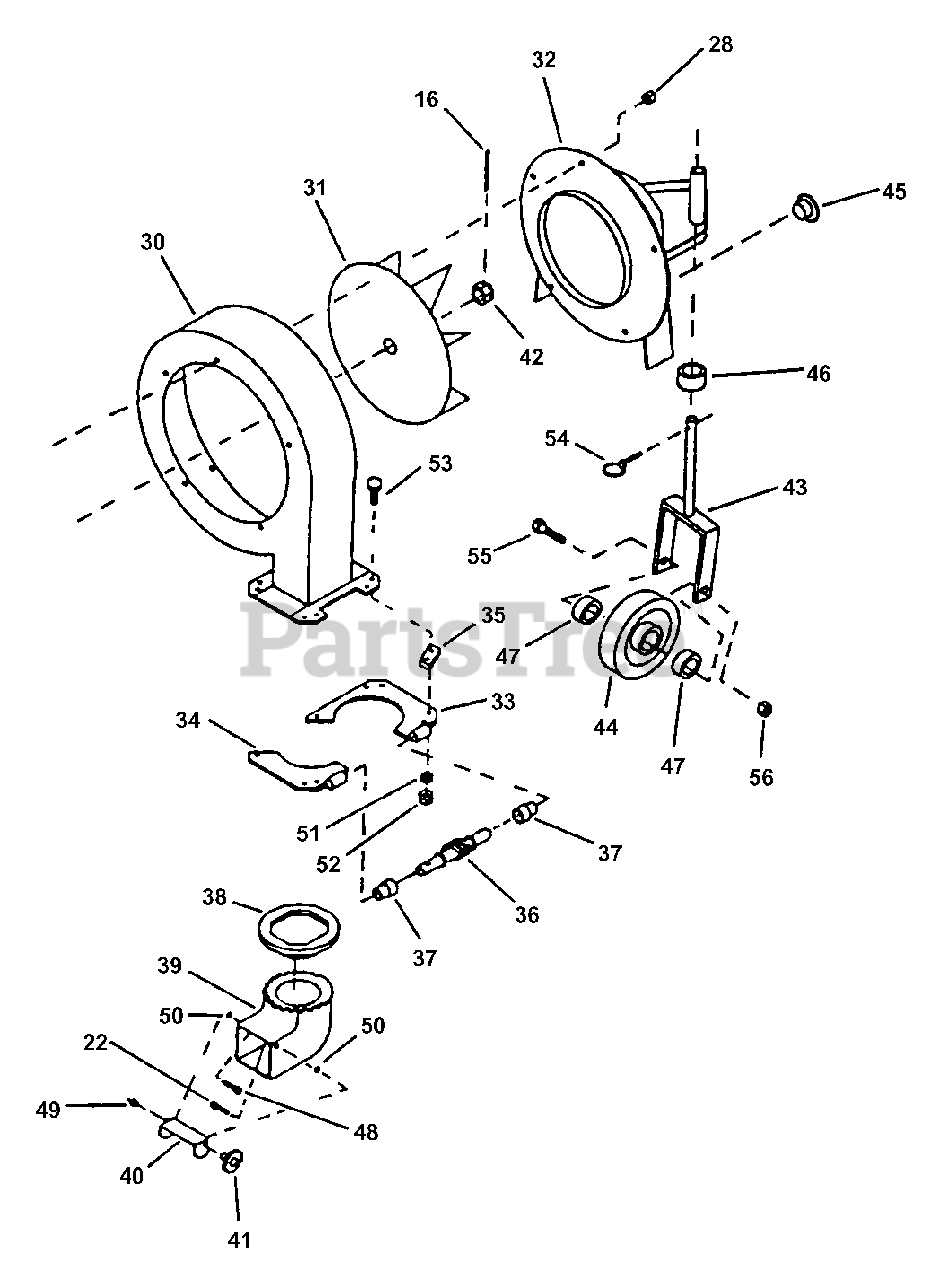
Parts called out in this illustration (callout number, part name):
16	PIN, 3/16" Dia. x 2" Cotter
22	BOLT, 5/16-18 x 1" Square Neck Carriage
28	NUT, 5/16-18 Hex Flange Lock, Grade 5 or B
30	HOUSING, Impeller (weldment)
31	IMPELLER (weldment)
32	COVER, Intake (weldment)
33	BRACKET, Rotation
34	PLATE, Retaining
35	SPACER, Rotation
37	BUSHING, Plastic, 1-5/16" long
38	RING, Nylon
39	NOZZLE, Air Blast
40	DEFLECTOR
41	KNOB, 5/16"
42	NUT, 1" Castle
43	SUPPORT, Wheel (weldment)
44	ASSEMBLY, Wheel & Tire
46	SPACER (for wheel support)
47	SPACER (for wheel)
48	BOLT, 5/16-18 x 3/4" Square Neck Carriage, Grade 5
49	NUT, 5/16-18 Hex Nyloc
50	WASHER, 11/32" Diameter
51	WASHER, 1/4" Lock
52	NUT, 1/4-20 Hex, Grade 5 or B
53	BOLT, 1/4-20 x 1" Hex Head
54	LINCHPIN, 5/16" Diameter
55	BOLT, 5/8-18 x 5-1/2" Hex
56	NUT, 5/8-18 Hex Nyloc
